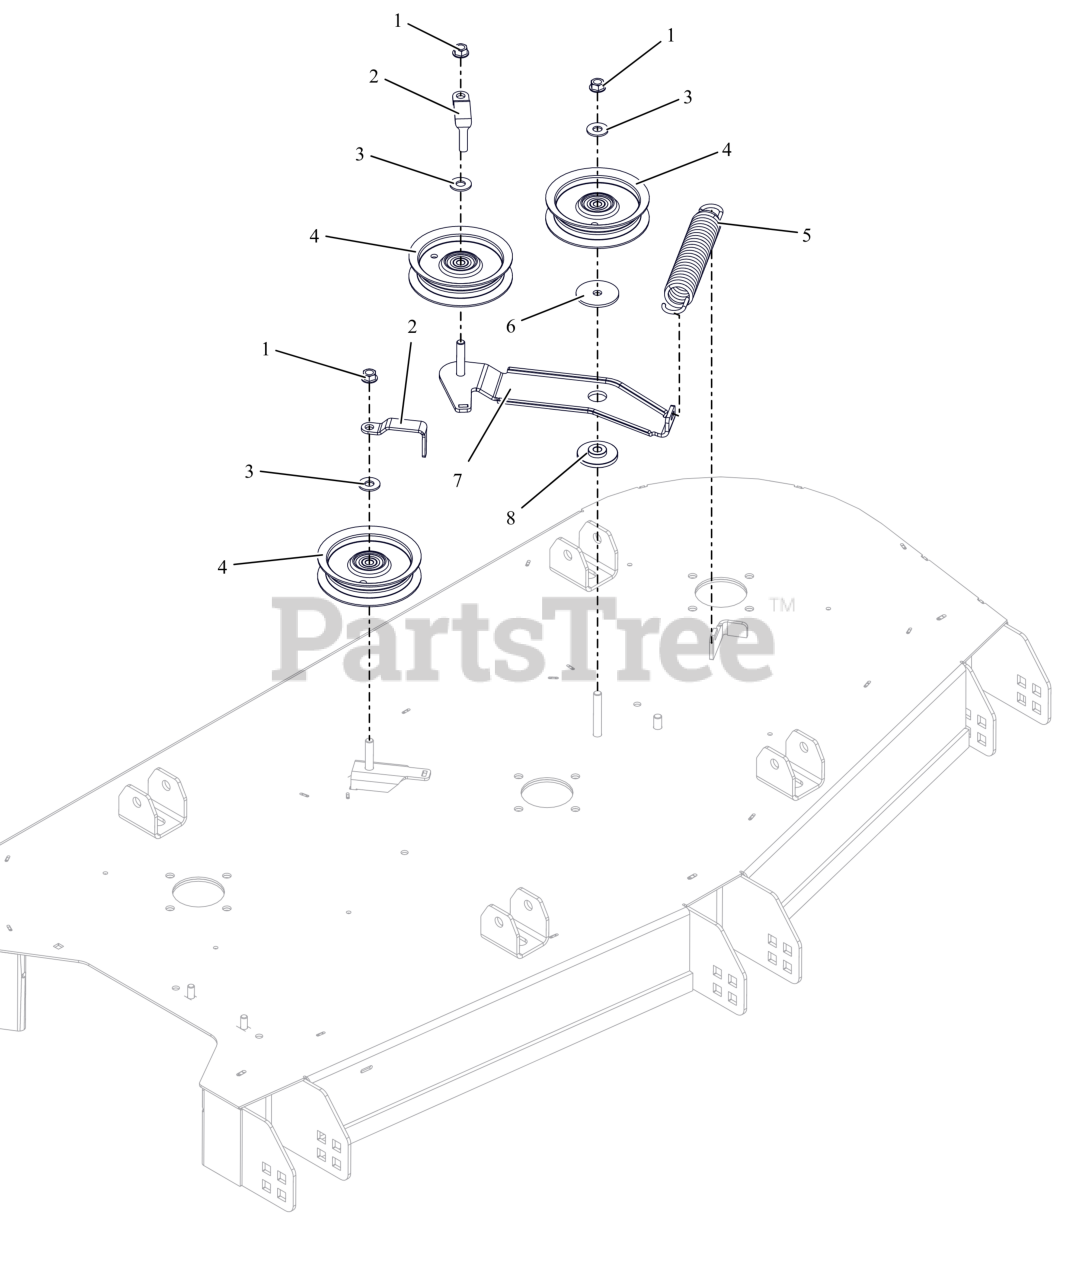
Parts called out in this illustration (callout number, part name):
1	NUT-LK-CTR-FLG .375-16 GF ZCC
2	FINGER, BELT (BLACK)
3	WSHR,FLT .438X1.00X.083 ZCC
4	IDLER, FLAT - 4.06" X .75"
5	SPRG, EXTENSION
6	WSHR-FL-STL 0.406X2X0.125 ZCC
7	WLDMT, TENSIONER ARM (BLACK)
8	BSHG-FLG .406X.88X.43X.25
